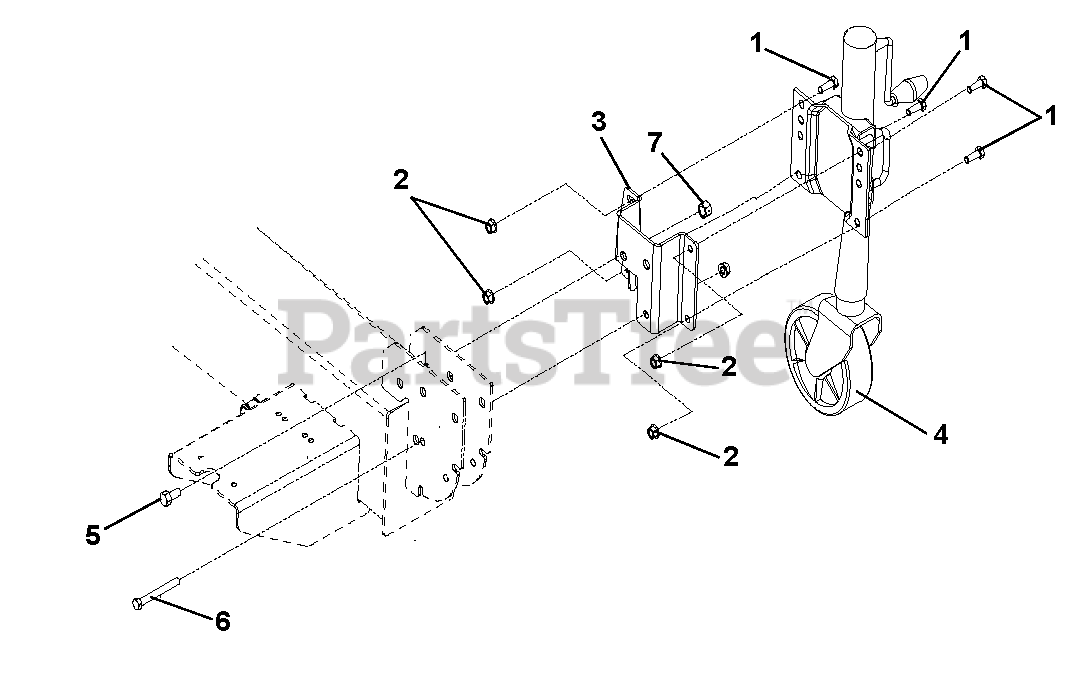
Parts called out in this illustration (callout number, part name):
1	Bolt, Hex .38-16 x 1.00 GR5
2	Nut, Top Flange Locking .38-16
3	Bracket, Mounting
4	Stand, Jack w/Wheel
5	Bolt, Hex .50-13 x 1.00
6	Bolt, Hex .38-16 x 3.25 GR5
7	Nut, Center Locking Flange .50-13
